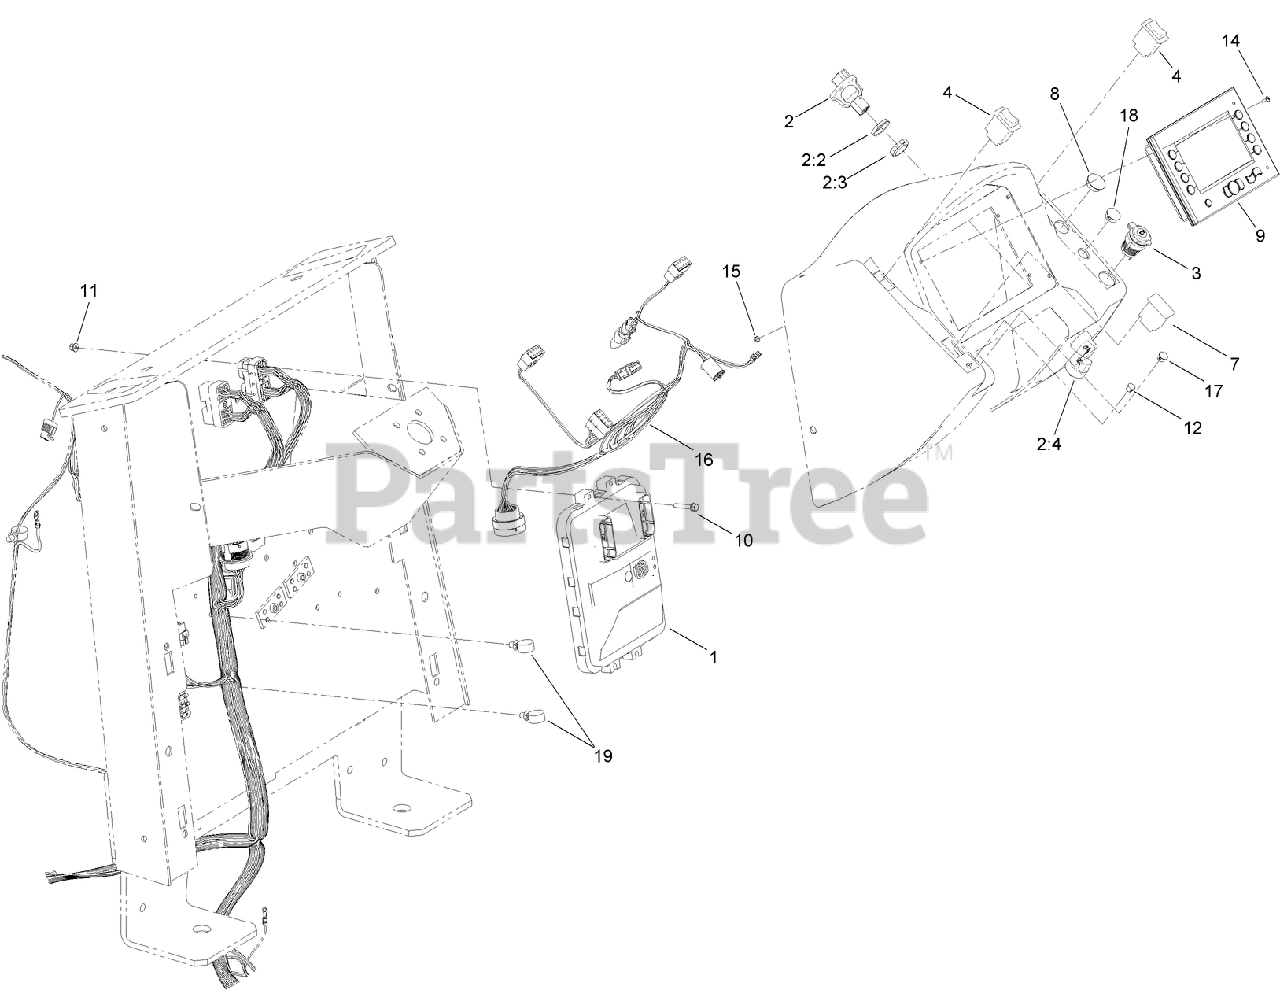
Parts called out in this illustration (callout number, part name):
1	CONTROLLER ASM (88 PIN, UNPROGRAMMED)
2	IGNITION SWITCH ASM
2:2	NUT-HEX
2:3	NUT-FACE
2:4	IGNITION KEY SET
3	RECEPTACLE-12V
4	SWITCH-ROCKER, 2 POLE (ON/OFF)
7	PLUG-PANEL
8	PLUG-DOME
9	DISPLAY-DP610TM, UNPROGRAMMED
10	SCREW-HHF
11	NUT-HHF
12	Plug-Dome
14	SCREW-PRH
15	NUT-HEX
16	HARNESS-DASH
17	PLUG-DOME
18	PLUG-DOME
19	CLIP-TIE
